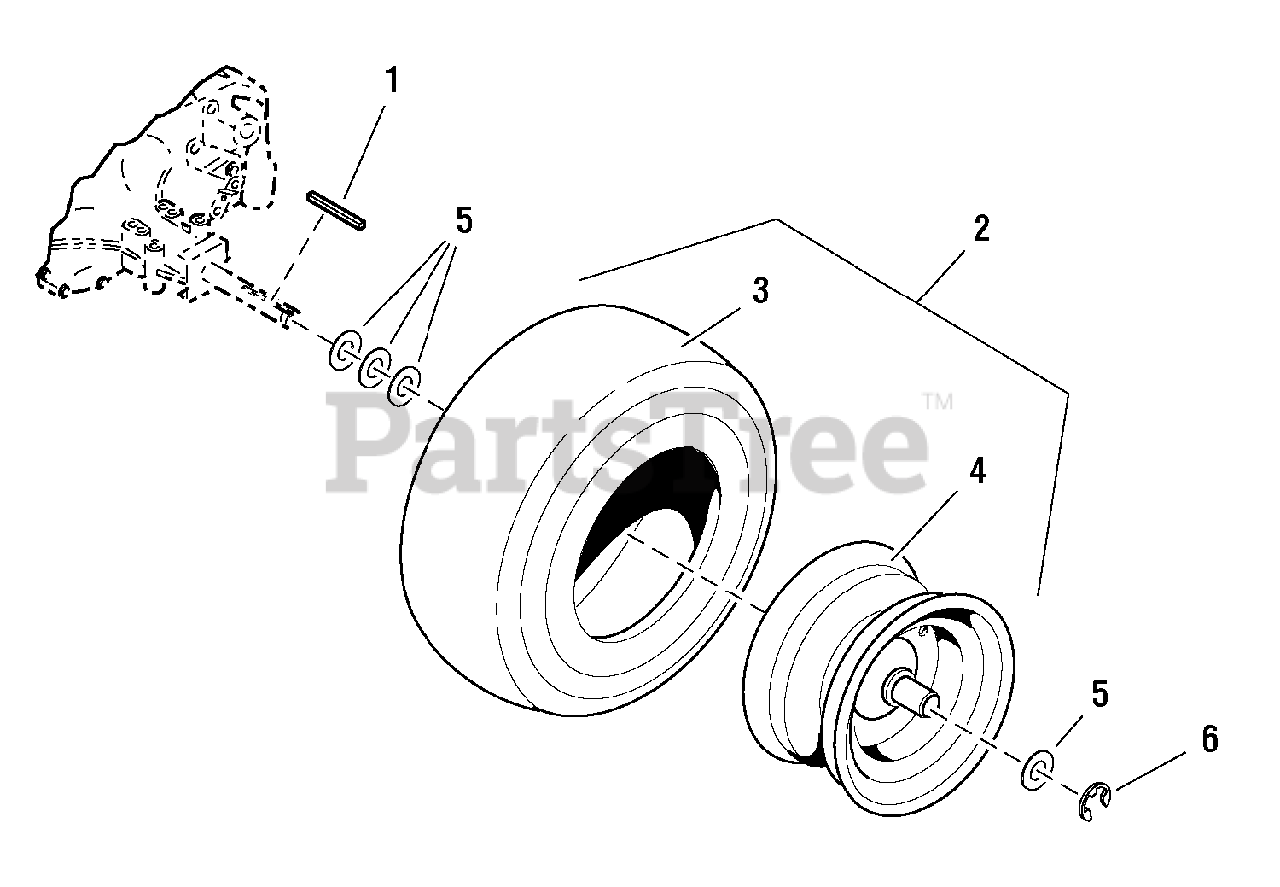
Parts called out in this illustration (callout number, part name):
2	WHEEL & TIRE ASSEMBLY, 16 x 6.5 x 8, Complete (Includes Ref. No. 3 & 4)
3	TIRE, 16. x 6.5 x 8
4	WHEEL ASSEMBLY, 8 x 5.38
